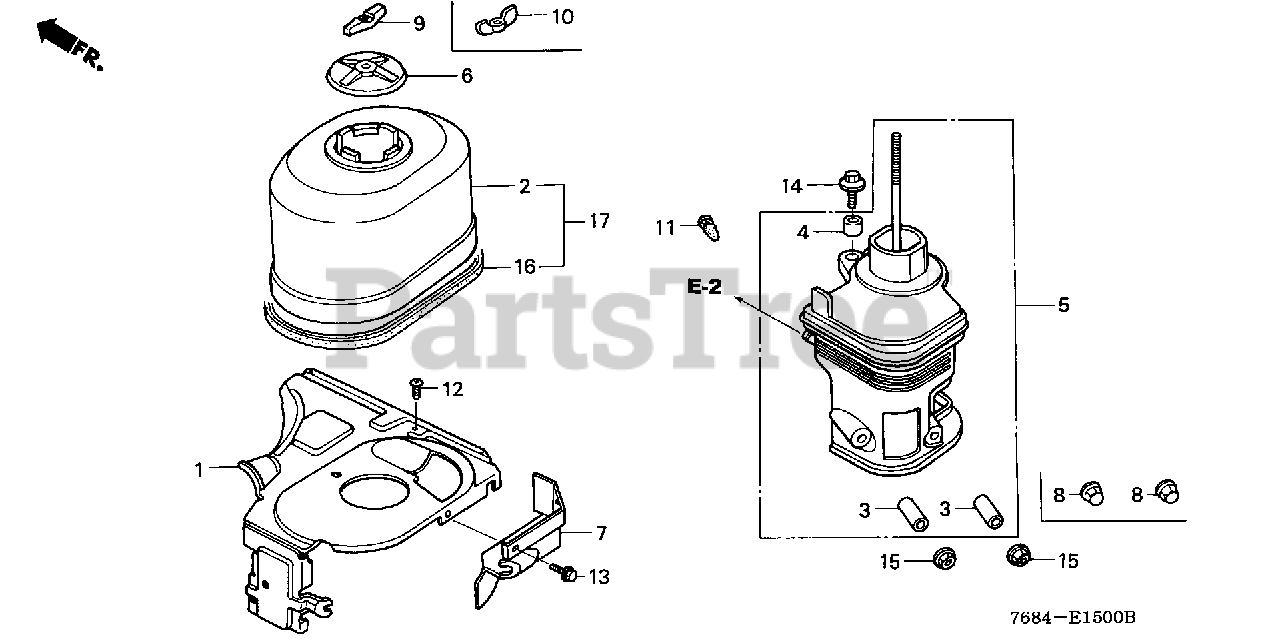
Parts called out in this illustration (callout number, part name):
1	COVER, CONTROL
2	COVER, AIR CLEANER (SEMI-DRY)
3	COLLAR, AIR CLEANER
4	COLLAR B, AIR CLEANER
5	ELBOW, AIR CLEANER
6	CAP, AIR CLEANER
7	COVER, AIR IN.
10	NUT, TOOL BOX SETTING
11	PLUG, CONE TYPE
12	SCREW, PAN (6X8)
13	BOLT, FLANGE (6X8)
15	NUT, FLANGE (6MM)
16	RUBBER, AIR CLEANER COVER
17	COVER, AIR CLEANER
